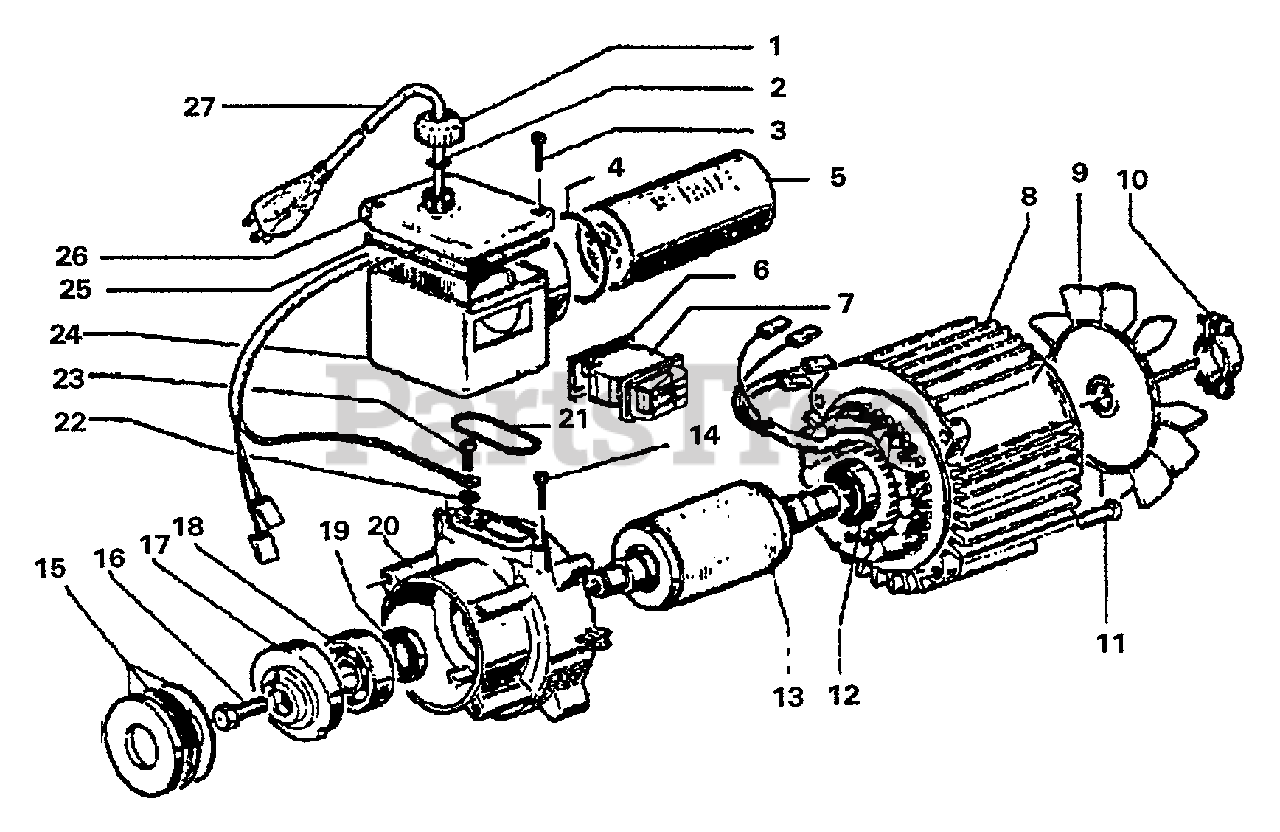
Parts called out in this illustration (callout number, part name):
1	WINGNUT - 1/2-14
2	O-RING - .296 X .084
3	SCREW - 4X18
4	O-RING, 1.925 X .103
5	CONDENSER
6	GASKET, SWITCH
7	SWITCH, IGNITION
8	STATOR
9	FAN
10	RING, LOCK
11	SCREW - 6X30
12	BEARING, BALL
13	ROTOR
14	SCREW - 4X13
15	AXLE, BEARING
16	SCREW
17	PLATE, CAM
18	BEARING, BALL
19	SEAL, OIL
20	CRANKCASE
21	O-RING - 1.549 X .103
22	WASHER
23	SCREW
24	COVER
25	O-RING - 3.237 X .103
26	COVER
27	CABLE ASSY
